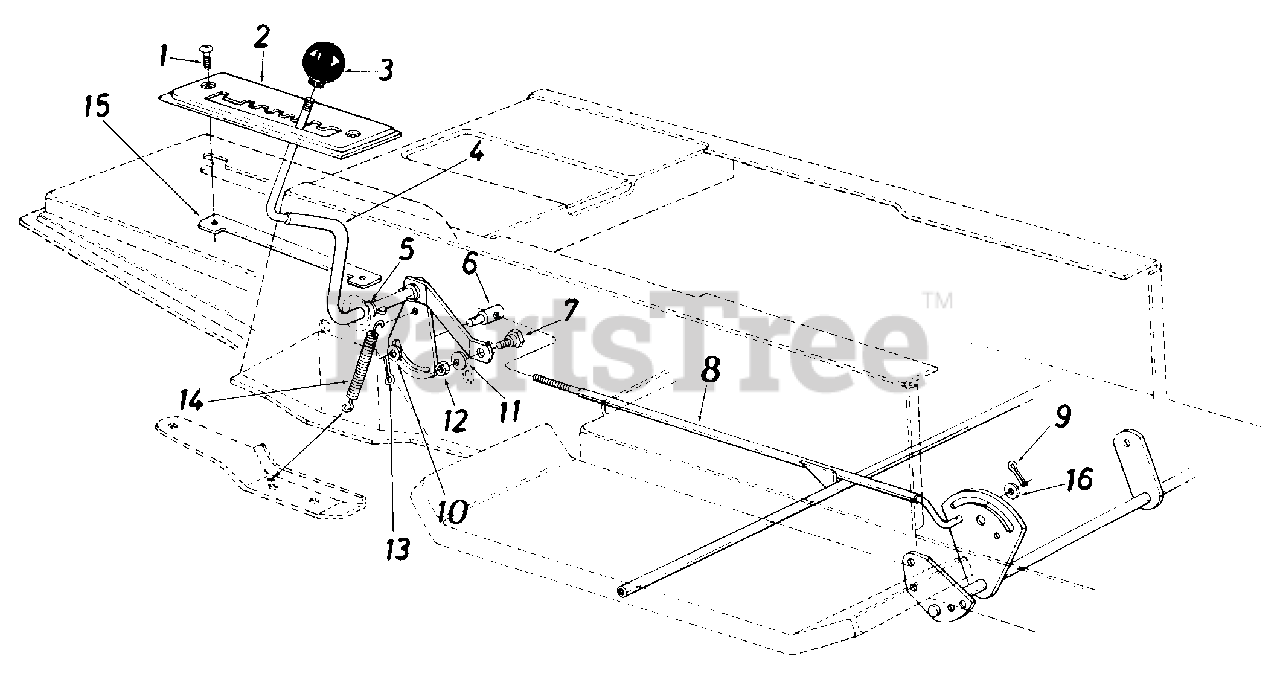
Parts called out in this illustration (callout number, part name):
1	Truss Mach. Scr. 1/4-20 x .75" Lg.
2	Speed Selector Plate 4-Speed
4	Speed Selector Cam Ass'y.
5	Flat Washer .53" I.D. x .93" O.D.
6	Ferrule 3/8-24 x .37" Dia.
7	Shoulder Bolt .435" Dia. x .160
8	Speed Control Rod Ass'y.
9	Cotter Pin 3132" Dia. x .75" Lg.*
10	Fl-Wash..39" I.D.
11	L-Wash. 5/16" I.D.
12	Hex Nut 5/16-18 Thd.*
13	Hairpin Cotter 1/8" Dia.
14	Spring
15	Clamping Plate
16	Fl-Wash. .47" I.D. x .88" O.D. x .063
